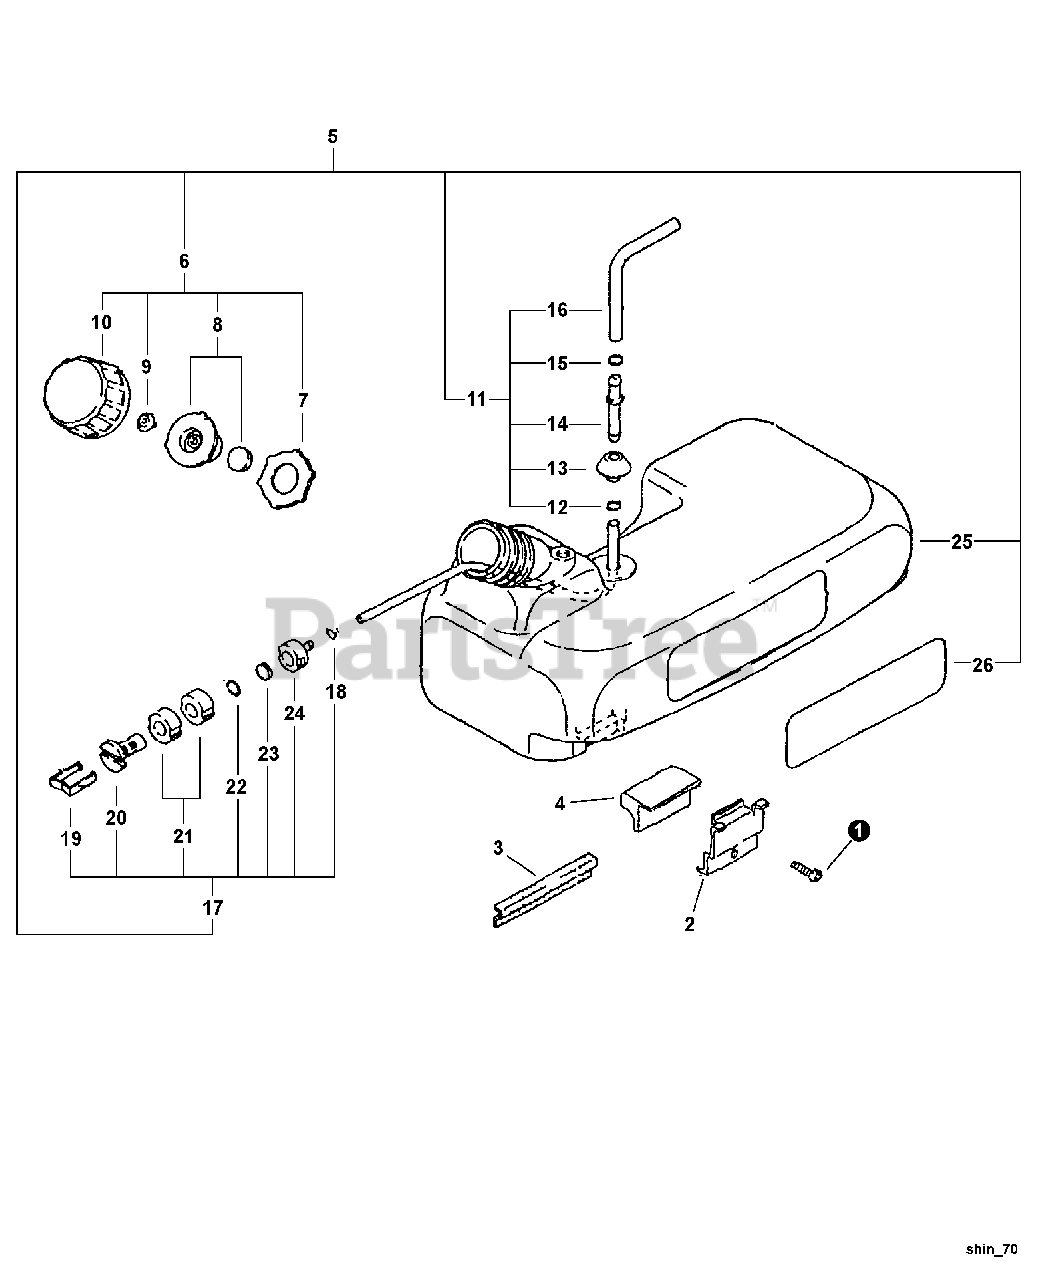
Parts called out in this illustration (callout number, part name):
1	SCREW - 5X10
2	BRACKET, TANK
3	CUSHION
5	FUEL TANK ASSY
6	CAP ASSY
7	GASKET
8	VENT RETAINER ASSY
9	VENT
10	CAP, FUEL
11	FUEL PIPE KIT
12	RING, RETAINING - 6
13	FUEL PIPE ASSY
14	CONNECTOR, PIPE
15	RING, RETAINING - 6
16	PIPE - FUEL
17	FILTER, FUEL
18	RING, RETAINING
19	CLIP, FILTER
20	CASE, FILTER
21	FILTER, FUEL
22	RING, RETAINING
23	SCREEN, FILTER
24	WEIGHT, FUEL FILTER
25	TANK, FUEL
26	LABEL - MODEL
